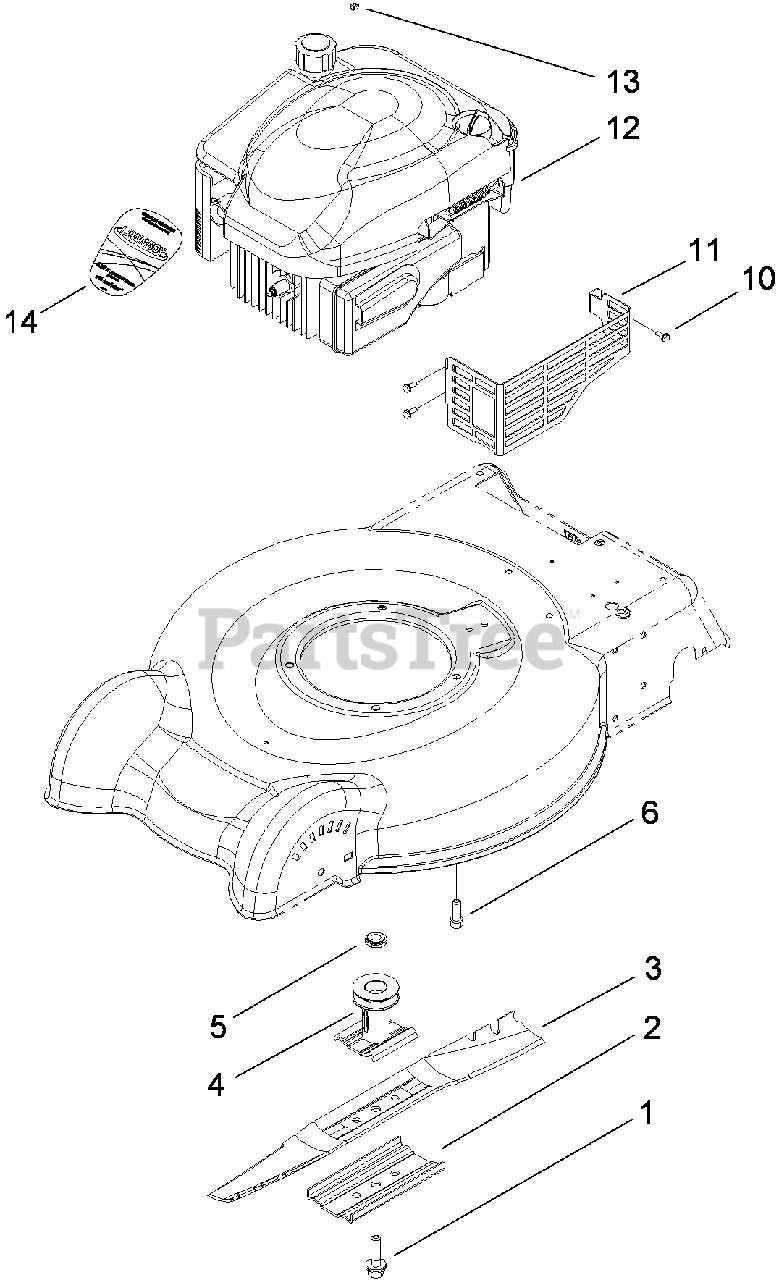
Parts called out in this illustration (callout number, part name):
1	BOLT-BLADE
2	SUPPORT-BLADE
3	BLADE-20 INCH
4	BLADE DRIVER ASM
5	Spacer-Driver
6	SCREW-TAPTITE
10	SCREW-TAPTITE
11	SHIELD-MUFFLER
13	STOP-ROPE
